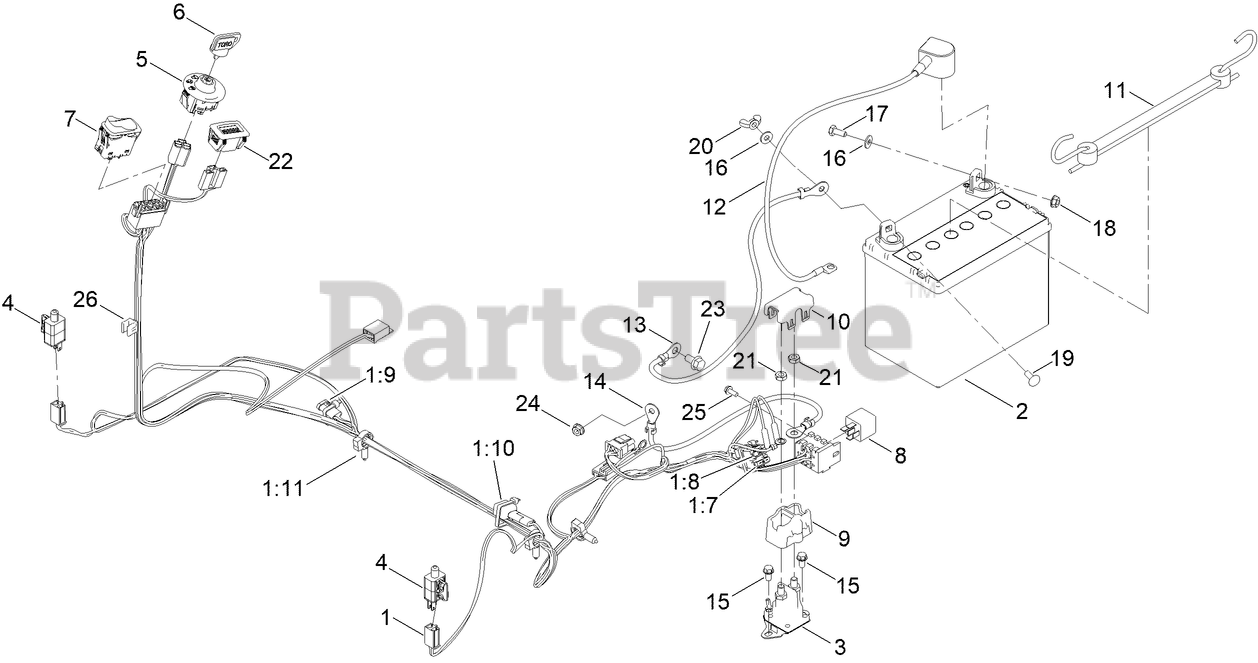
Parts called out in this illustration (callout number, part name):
1	HARNESS-WIRE, MAIN
1:7	FUSE-BLADE, 15 AMP
1:8	FUSE-BLADE, 25 AMP
1:9	CAP-OVER MOLD, 1M/1F
1:11	CLIP-TUBING, HARNESS
2	BATTERY- WET, 12V, 300 CCA
3	SOLENOID
4	SWITCH
5	SWITCH-IGNITION
6	KEY-IGNITION
7	SWITCH-ROCKER, ON-NONE-ON
9	COVER-SOLENOID
10	CAP-SOLENOID
11	HOLDDOWN-BATTERY
12	CABLE-BATTERY,RED
13	CABLE-BATTERY, BLACK
14	CABLE-BATTERY, POSITIVE
15	SCREW-HWH
16	WASHER
17	SCREW-HH
18	NUT-HF
19	BOLT-CARR
20	NUT-WING
21	NUT-HJ
22	HOUR METER
23	SCREW-HHF
24	NUT-HF
25	SCREW-TAPTITE
26	CLIP-EDGE W/TIE, PERPENDICULAR
